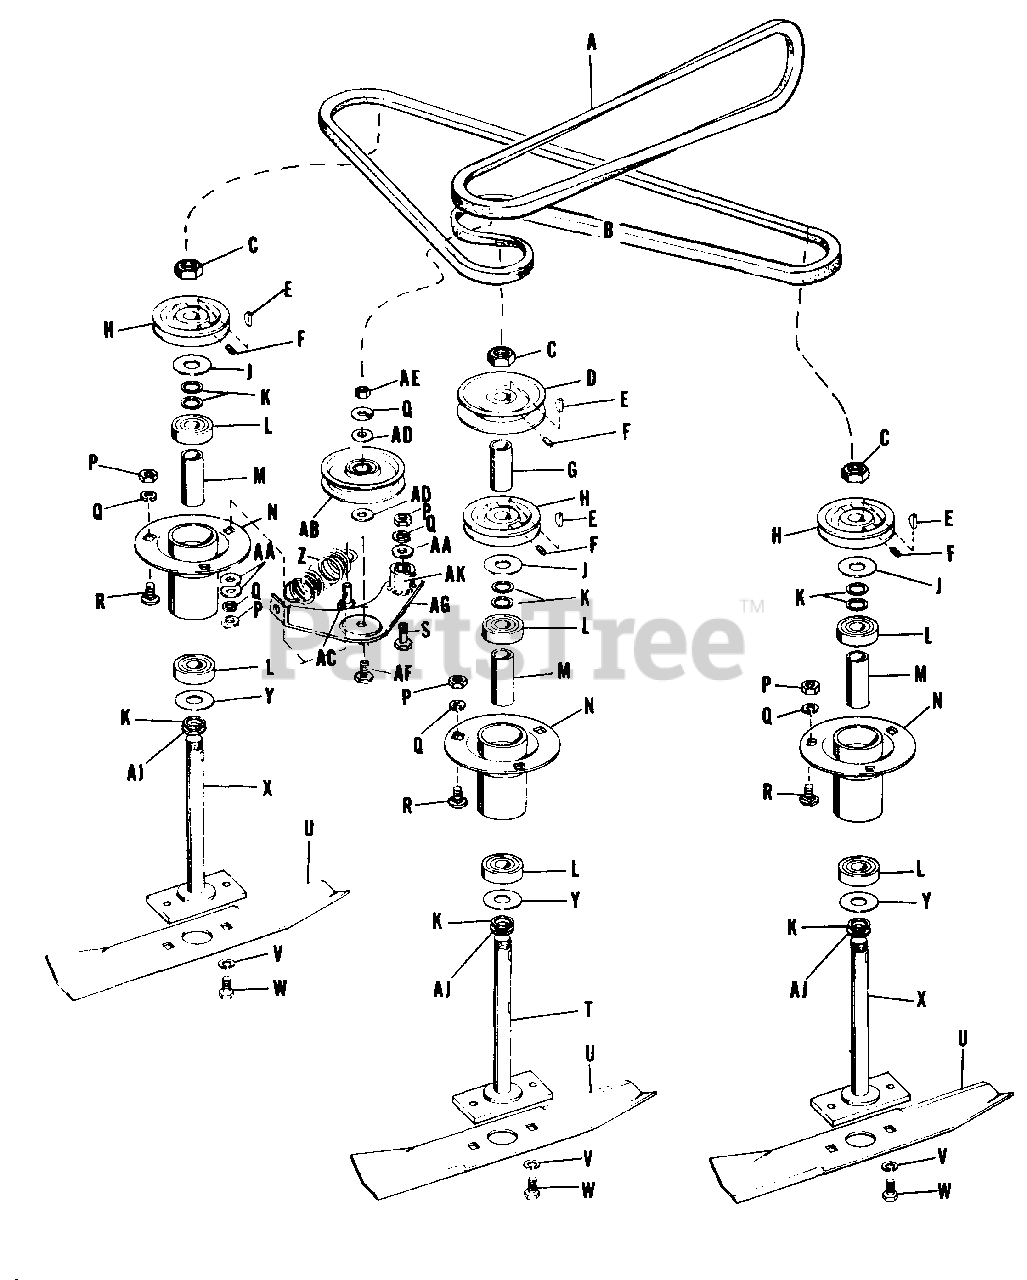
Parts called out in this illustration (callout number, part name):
A	Belt, "V" (Cross Drive)
B	Belt, "V" (Mower Spindle Drive)
C	Hex. Jam Lock Nut, 3/4"-16
D	Cross Drive Pulley
E	Key, Woodruff, #61
F	Set Screw, 5/16"-18 x 3/8"
N	Arbor Tube Assembly
P	Full Hex. Nut. 3/8"-16
Q	Lock Washer, 3/8"
R	Carriage Bolt, 3/8"-16 x 3/4"
S	Hex. Cap Screw 3/8-16 x 1-3/4" lg.
T	Arbor Drive Assembly
U	Knife Blade
V	Lock Washer, 3/8"
W	Hex. Hd. Capscrew, 3/8"-16 x 5/8"
X	Arbor Assembly
AA	Plain Washer, 5/16"
AB	Idler Pulley
AD	Plain Washer, 5/16"
AE	Full Lock Hex. Nut, 3/8"-16
AG	Idler Lever Assembly
